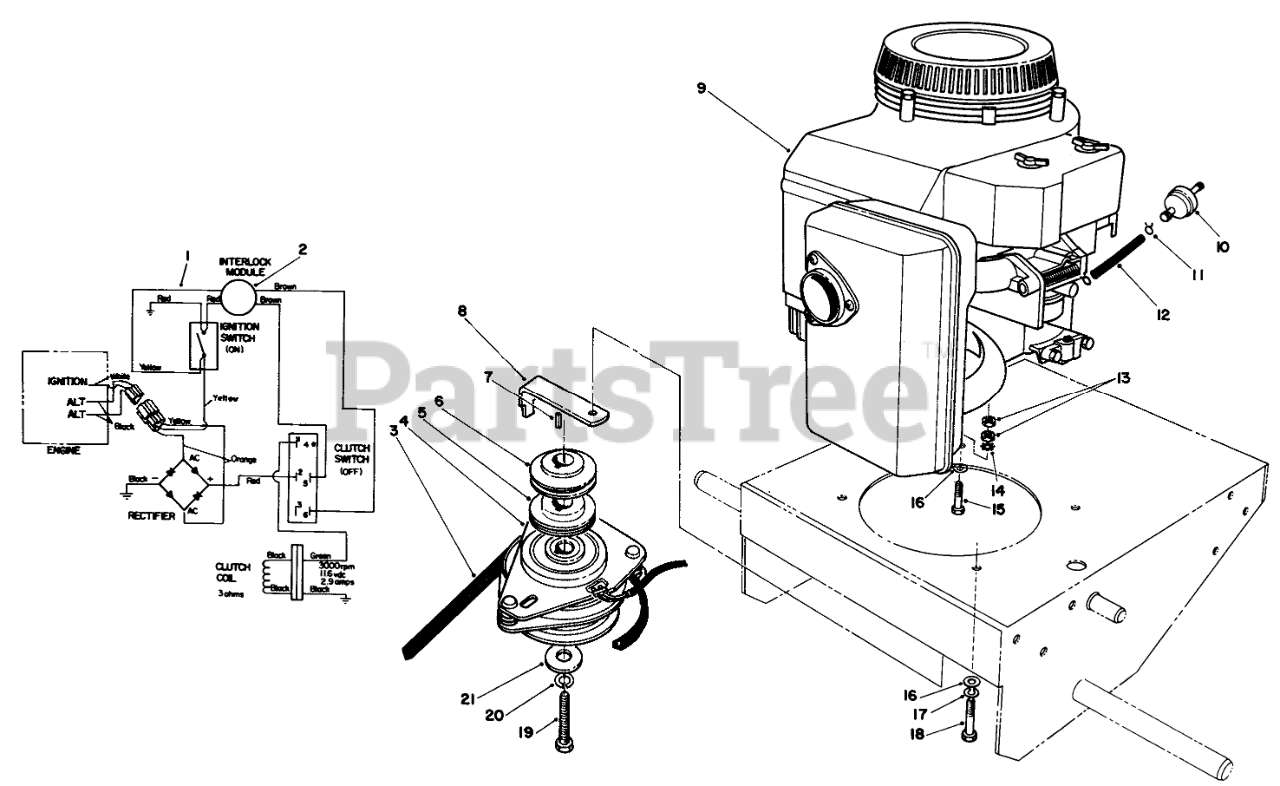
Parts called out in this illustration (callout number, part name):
1	WIRE HARNESS
2	Module
3	V-BELT, DRIVE
4	CLUTCH/BRAKE
5	SHEAVE-LOWER HALF
6	SHEAVE-UPPER HALF
7	KEY-SQUARE
8	Retainer-Clutch
10	FILTER-FUEL
11	CLAMP-HOSE
12	HOSE-FUEL
13	NUT-JAM
14	WASHER-LOCK
15	SCREW (ENGINE, GROUND)
16	WASHER-PLAIN
17	WASHER-LOCK
18	SCREW-HH
19	SCREW-CLUTCH
20	WASHER-LOCK
21	WASHER-CLUTCH
